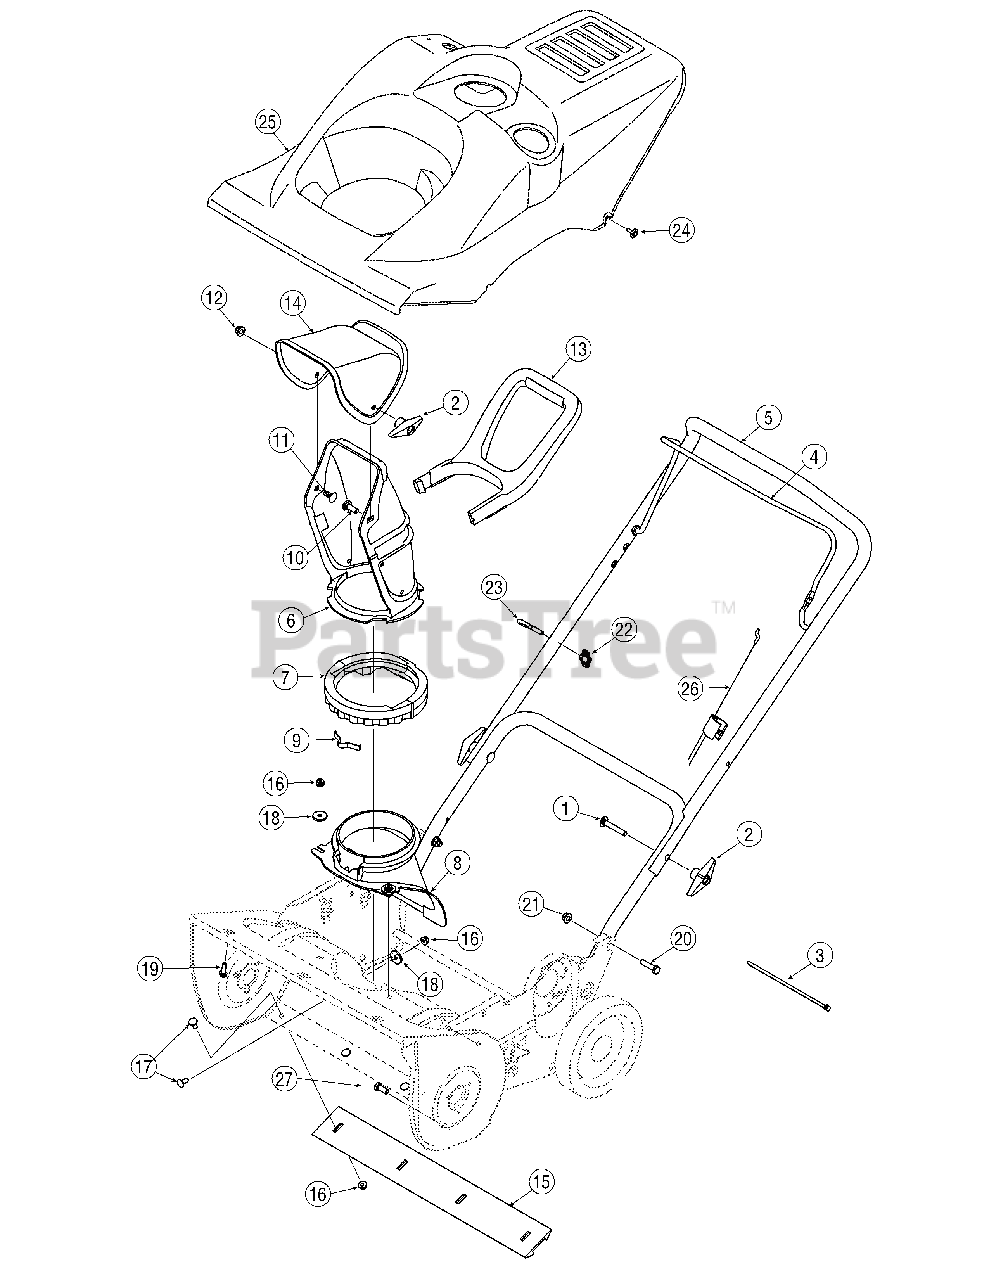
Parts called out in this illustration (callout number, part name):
1	Carriage Screw, 5/16-18 x 2.00
2	Wing Knob, 5/16-18
3	Cable Tie, 3/16 x .05 x 7.4
4	Bail Control
5	Upper Handle
6	Lower Chute
7	Chute Ring
8	Chute Adapter
9	Chute Adjustment Spring
10	Carriage Bolt. 5/16-18 x 1.00
11	Carriage Bolt. 5/16-18 x .750
12	Flange Lock Nut, 5/16-18
13	Chute Handle
14	Upper Chute
15	Shave Plate, 21"
16	Flange Lock Nut, 1/4-20
17	Carriage Screw, 1/4-20
18	Flat Washer, .265 x .938 x .120
19	Hex Screw, 5/16-18 x .750
20	Hex Screw, 5/16-18 x 1.25
21	Flange Lock Nut, 5/16-18
22	Handle Knob
23	Eye Bolt, 1/4-20
24	Hex Screw, 10-16 x .625
25	Shroud
26	Clutch Cable
27	Hex Screw, 5/16-18 x .75
